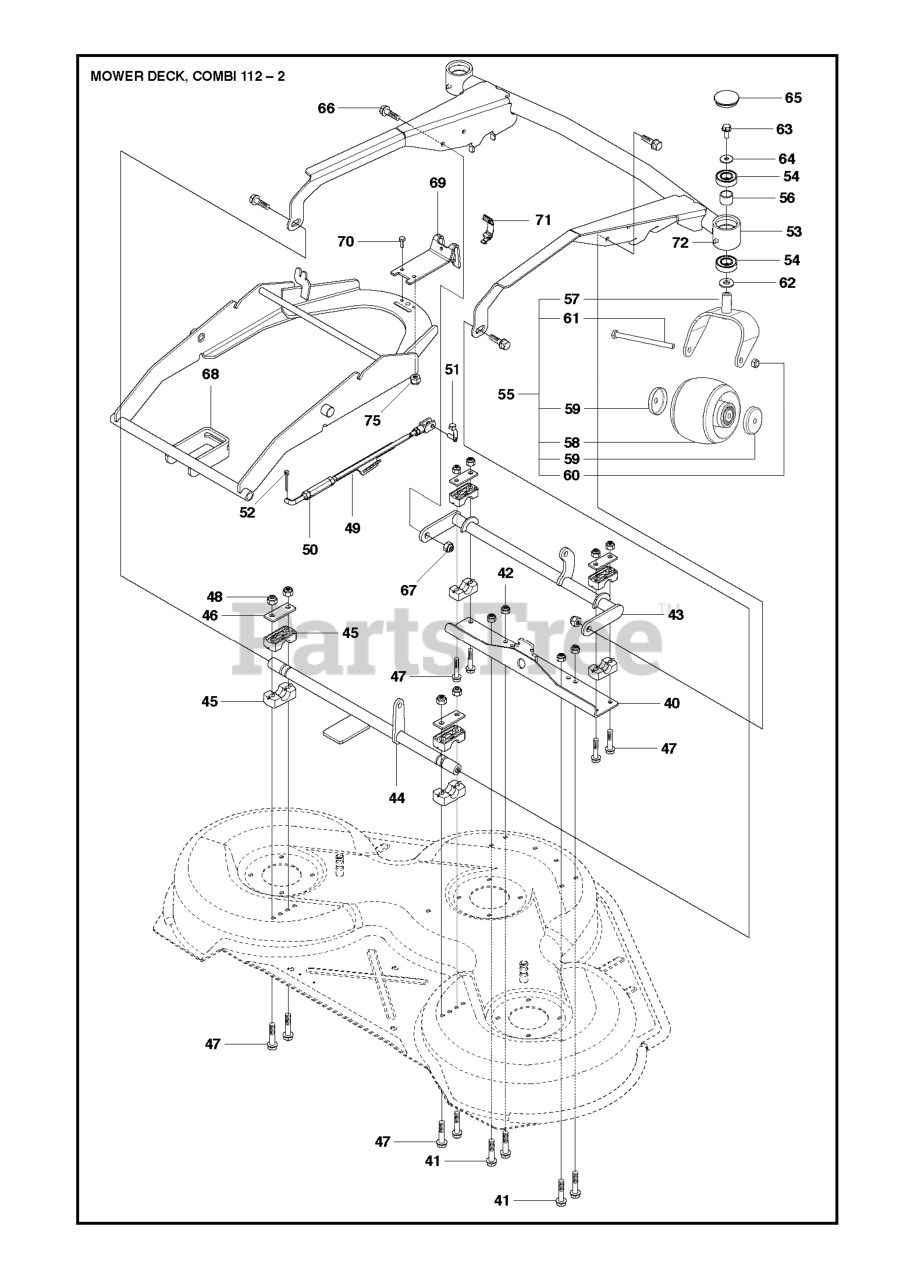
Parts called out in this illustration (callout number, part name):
42	LOCKNUT M8
48	LOCKNUT M8
50	PARALLEL ROD
54	BALL BEARING 6004-2RS1
61	BOLT
64	SPACER
65	HUB CAP PIVOT WHEEL
67	LOCKNUT M8
70	SCREW
72	GREASE NIPPLE
75	CLIP GRAY
